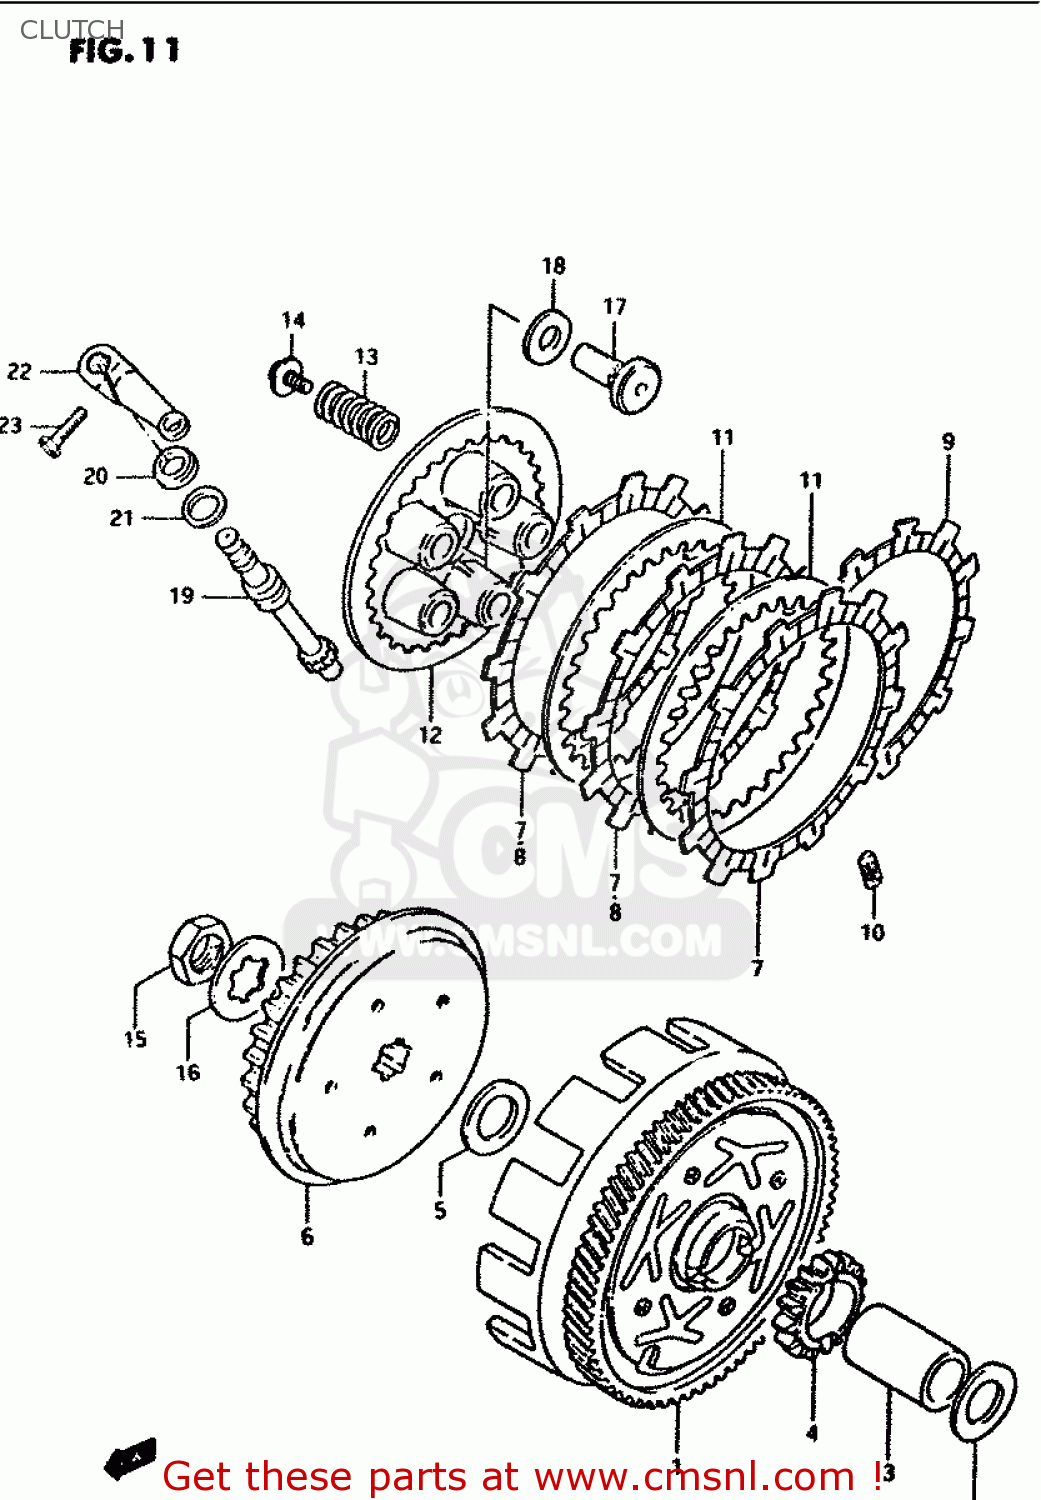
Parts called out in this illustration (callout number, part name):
1	GEAR ASSY,PRI DRIVEN(NT:73)
2	WASHER,THRUST
3	SPACER
4	GEAR,KICK STARTER DRIVE
5	WASHER
6	HUB,CLUTCH SLEEVE
7	PLATE,CLUTCH DRIVE (NAS)
8	PLATE,CLUTCH DRIVE (NAS)
9	PLATE,CLUTCH DRIVE (NAS)
10	DAMPER
11	PLATE,CLUTCH DRIVEN (NAS)
12	DISC,CLUTCH PRESSURE
13	SPRING
14	BOLT 5X16
15	NUT
16	WASHER,LOCK
17	RACK,CLUTCH RELEASE
18	BEARING(10X22X2.8)
19	PINION,CLUTCH RELEASE
20	SEAL,OIL(10X17X5)
21	WASHER (12X17X1)
22	ARM,CLUTCH RELEASE
23	BOLT
